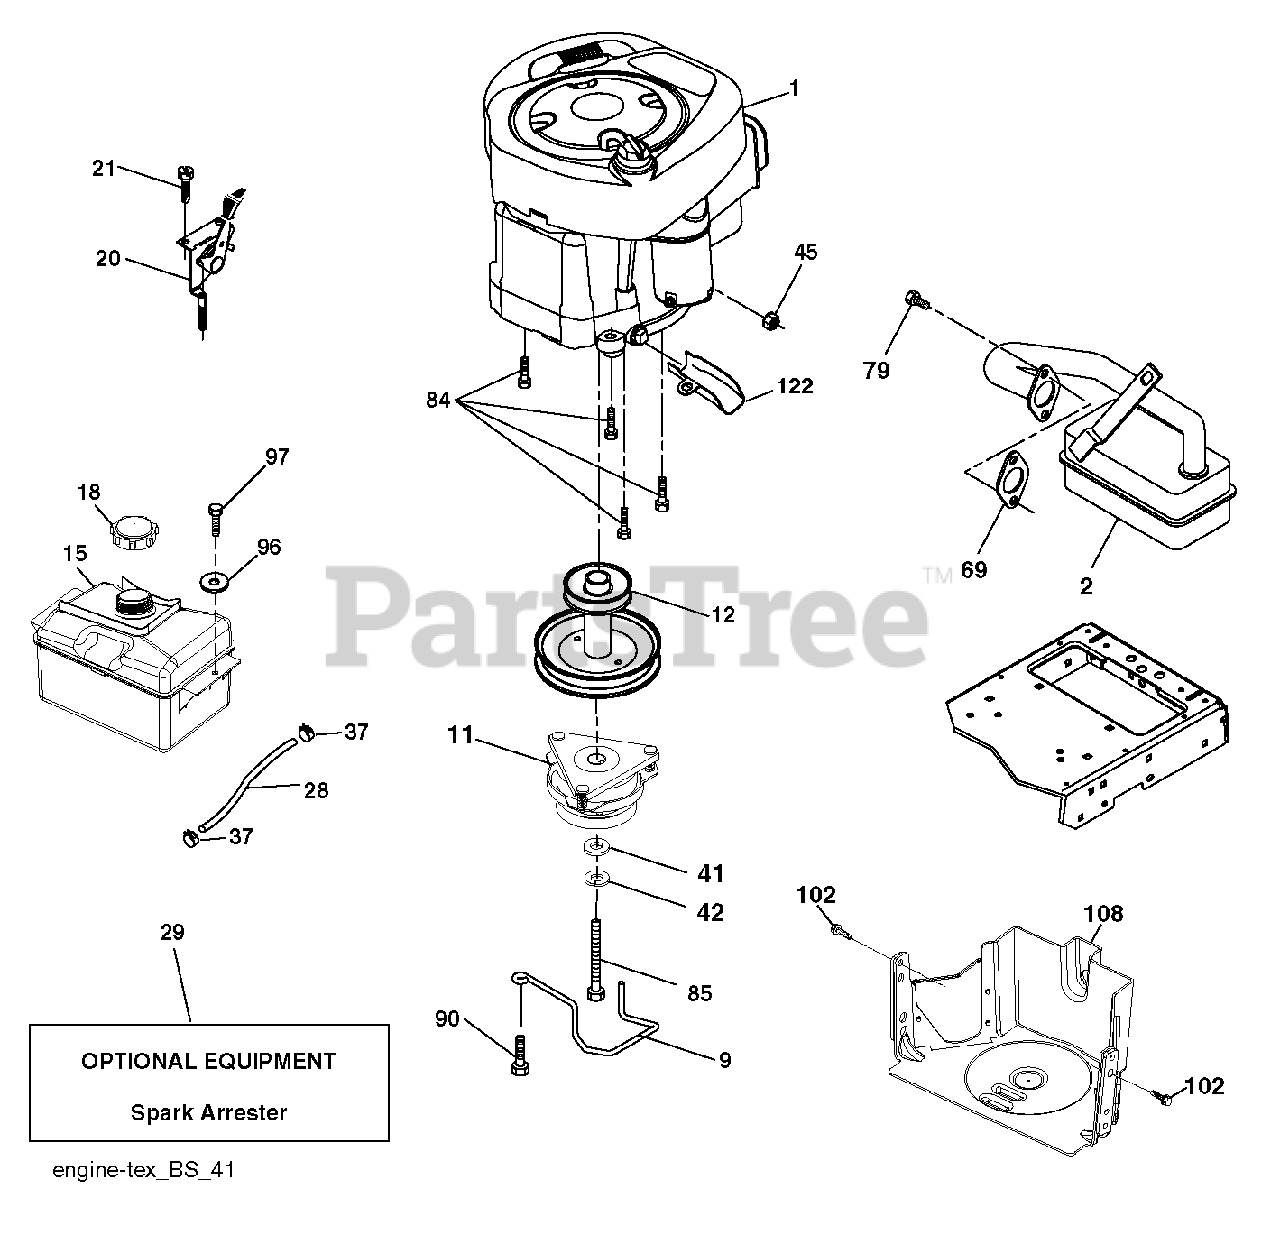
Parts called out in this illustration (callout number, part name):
9	KEEPER.BELT.ENGINE.3.25
11	CLUTCH
12	PULLEY.ASM.ENG.OGURA.3
15	TANK FUEL FRT 1.5 GAL
18	CAP ASM.FUEL.2.25"FR.
20	CONTROL.TH/CK.C.
21	SCREW.#10 X 0.750.BOS THREAD
28	LINE.FUEL.20
29	ARRESTER SPARK (OPTIONAL)
37	HOSE CLAMP
42	LOCKWASHER
45	NUT
69	REPL BY 532 27 22-93
79	SCREW.SOCKET HD.5/16-1
84	SCREW.3/8-16
85	BOLT HEX 7/16-20X4-1/4"
90	SCREW 3/8-16X1
96	WASHER
97	SCREW HEXWSHR 1/4-20X3/4
102	SCREW
122	EXTENSION DRAIN OIL
